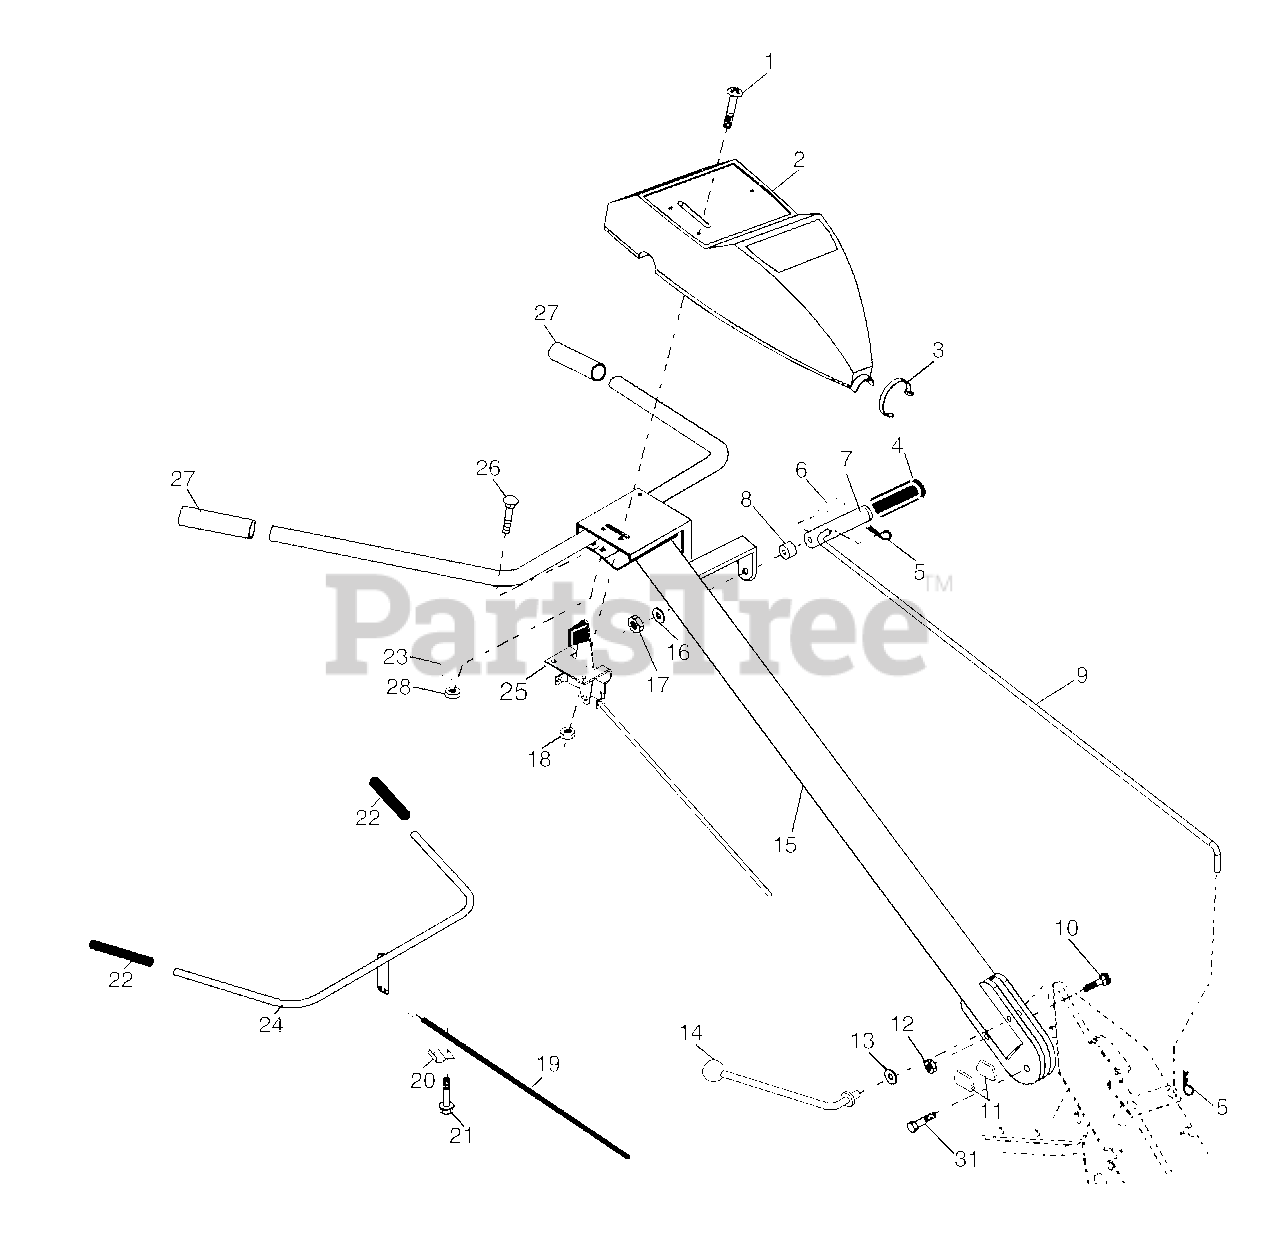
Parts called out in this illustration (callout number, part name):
1	Screw, Phd. #10-24 UNC
2	Panel, Control
3	Tie, Cable
4	Grip, Handle
5	Clip, Hairpin
6	Bolt, Shoulder
7	Handle, Shift
8	Grommet, Rubber
9	Rod, Shift
10	Bolt, Carriage 3/8-16 x 1 Gr. 5
11	Lock, Handle
12	Nut, Centerlock 3/8-16
13	Washer 13/32 x 1 x 11 Ga.
14	Lever, Lock, Handle
15	Handle
16	Washer, Lock 1/4
17	Nut, Hex 1/4-20
18	Nut, Keps #10-24 UNC
19	Cable, Clutch
21	Screw, Hex Washer Hd. Slotted #10-24 x 1/2
22	Grip, Bar, Control
23	Clamp, Bar, Control
24	Bar Assembly, Control
25	Control, Throttle
26	Bolt, Carriage 1/4-20 UNC x 1/2
27	Grip, Handle
28	Nut, Keps Hex 1/4-20
31	Bolt Pivot
